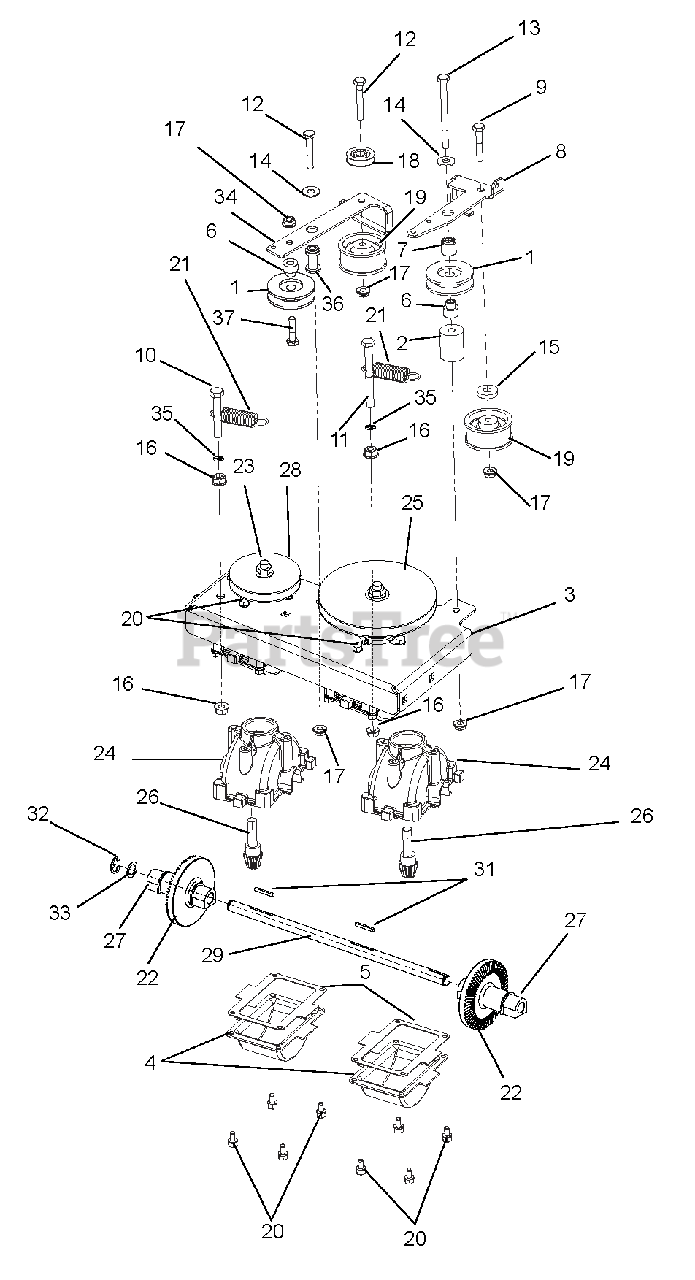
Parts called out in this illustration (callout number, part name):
1	IDLER, 3L FRONT SIDE .38X1.875
2	SPACER, REVERSE IDLER
3	PLATE, TRANSMISSION MOUNT
4	SUMP, GEARBOX
5	GASKET, TRANSMISSION
6	SPACER, V-IDLER PULLEY
7	SPACER, IDLER ARM
8	BRKT-TRANS IDLER ARM
9	@BLT-HEX .25-20X1.50 GR5 YWZC
10	@BLT-HEX .31-18X2.50 GR5 YWZC
11	@BLT-HEX .31-18X3.50 GR5 YWZC
12	@BLT-HEX .25-20X1.75 GR5 YWZC
13	@BLT-HEX .25-20X3.25 YWZC
14	@WSHR-FL-STL.312X.734X.065 YWZ
15	WSHR-FL-STL .328X.87X.179 YWZC
16	@NUT-SPNLK-FLG .312-18 YWZC
17	@NUT-LK-TOP-FLG .25-20 YWZC
18	PULLEY, CABLE
19	PULLEY, ILDER .25X1.875X.97
20	SCR-TAP 10-24X.375 PRE-COAT 80
21	SPRG, TENSION .063X.625X2.50
22	GEAR, BEVEL (CU INFL, KEYWAY)
23	@NUT-LK-TOP-FLG .38-16 YWZC
24	HOUSING, WBLM GEAR BOX
25	PULLEY, WAW REVERSE INPUT
26	PINION, GEARBOX INPUT
27	BUSHING, TRANS OUTPUT SHAFT
28	PULLEY, WAW INPUT
29	SHAFT-TRANS OUTPUT
30	KIT, WAW TRANSMISSION SHAFT
31	KEY, 1/8 X 1/8 X 1.0
32	RG-RTNG-EXT .500X.042 (E)
33	WASHER, .500X.750X.020 THRUST
34	ARM, DOUBLE ACTING IDLER
35	NUT-PUSH .312
36	PIVOT, IDLER
37	@BLT-HEX .25-20X1.25 GR5 YWZC
